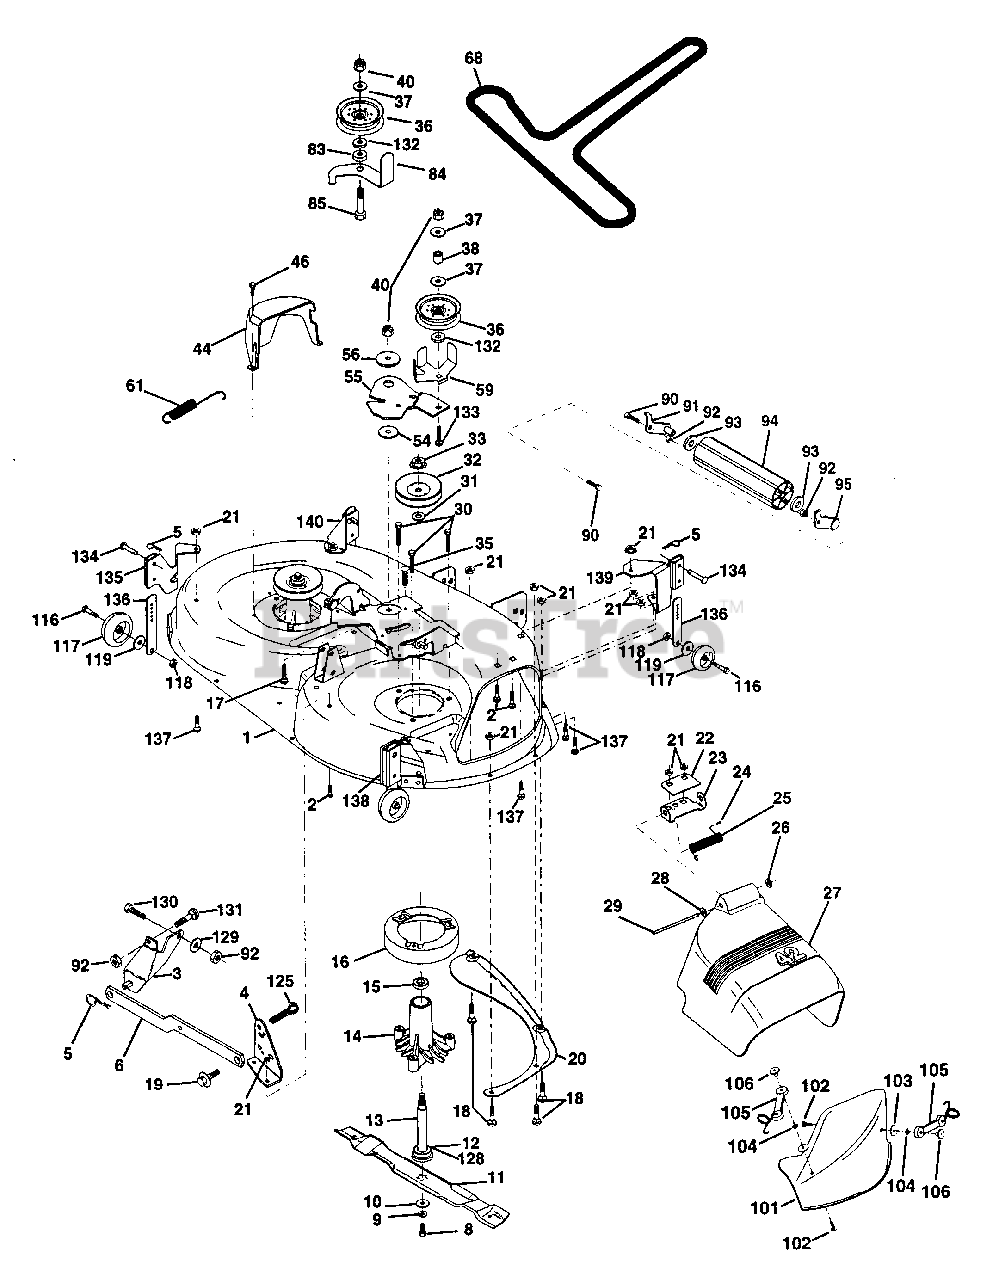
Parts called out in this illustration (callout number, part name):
1	Deck Weldment Mower 42" W/Adj
2	Bolt Rdhd Sqnk 5/16-18 unc X 3/4
3	Bracket Asm Fr Sway Bar 38/42
4	Bracket Asm Deck 42" sway Bar
5	Retainer Spring
6	Arm Suspension Rear
8	Bolt 3/8-24 x 1 25 Gr8 Patched
9	Washer Lock Hvy 3/8 Unplated
10	Washer Hard Blade Mower Vented
11	Blade Mower Mulching 42"
12	Bearing Ball #6204 (Mandrel)
13	Shaft Asm W/lower Bearing
14	Housing Mandrel Vented (machd)
15	Bearing Ball Mandrel
16	Stripper Round Mower
17	Bolt Rdhd Sqnk 3/8-16 X 2-1/4
18	Bolt Carr 5/16-18 X 5/8
19	Bolt Shoulder
20	Baffle Vortex 42
21	Nut Crown Lock 5/16-18
22	Stiffener Bracket 42" deck
23	Bracket Deflector Mower 42"
24	Cap Sleeve 80 x 112 Blk Mower
25	Spring Torsion Deflector 2 52
26	Nut Push Phos & Oil
27	Shield Deflector Mower 42" Blk
28	Washer 11/32 X 5/8 X 16 Ga
29	Rod Hinge 42"6 75 Wlg
30	Screw Thdrol Washer Head
31	Washer Spacer Mower Vented
32	Pulley Mandrel 42"
33	Nut 9/16top Lock Flng Cntr
35	Fastner Christmas Tree
36	Pulley Idler Flat 3 060
37	Washer 13/32 X 13/16 X 16 Ga
38	Spacer Spring Stop Idler
40	Nut Lock 3/8-16 Unc
44	Guard Mandrel LH Black
46	Screw Thdrol 1/4-20 x 5/8
54	Washer Hardened
55	Arm Idler 42"mower LT/YT
56	Spacer Retainer Pm Mower
59	Guard, Belt
61	Spring Ext. Elect
68	V-Belt Mower
83	Washer Sintered
84	Keeper Belt Idler
85	Bolt Carriage 3/8-16 x 2-1/2 Gr.5
90	Bolt Fin Hex 3/8-16unc X 1
91	Bracket Asm Noseroller LH
92	Nut Lock Hex w/ins. 3/8-16 UNC
93	Washer 17/32 X 7/8 X 16 Ga
94	Roller Nose 38 & 42
95	Bracket Asm Noseroller RH
101	Cover Mulching 42" Blk
102	Screw
103	Washer #10
104	Washer Lock #10
105	Latch Asm Bagger
106	Nut Weld .327/.304 #10-24
116	Bolt Shld
117	Wheel Gauge blk.
118	Nut Centerlock 3/8 - 16 UNC
119	Washer 3/8 x 7/8 x 14 Ga.
125	Cotter Pin
128	Washer Felt
129	Washer 13/32 x 13/16 x 12 Ga.
130	Bolt Fin Hex 3/8-16 UNC x 1 Gr. 5
131	Bolt Rdhd Sqnk 3/8-16 Unc x 1
132	Washer 13/32 x 1-3/8 x 3 Ga
133	Bolt Rdhd 3/8-16 UNC x 2-3/4 Gr.5
134	Pin Head Rivet
135	Bracket Asm Whl Ga Rear LH 42"
136	Bar Pnt Adjusting Wheel Gauge
137	Bolt Carr 5/16-18 x 5/8 Short
138	Bracket Asm Whl Ga. Rear RH 42"
139	Bracket Asm Whl Ga. Front RH 42"
140	Bracket Asm Whl Ga. Front RH 42"
